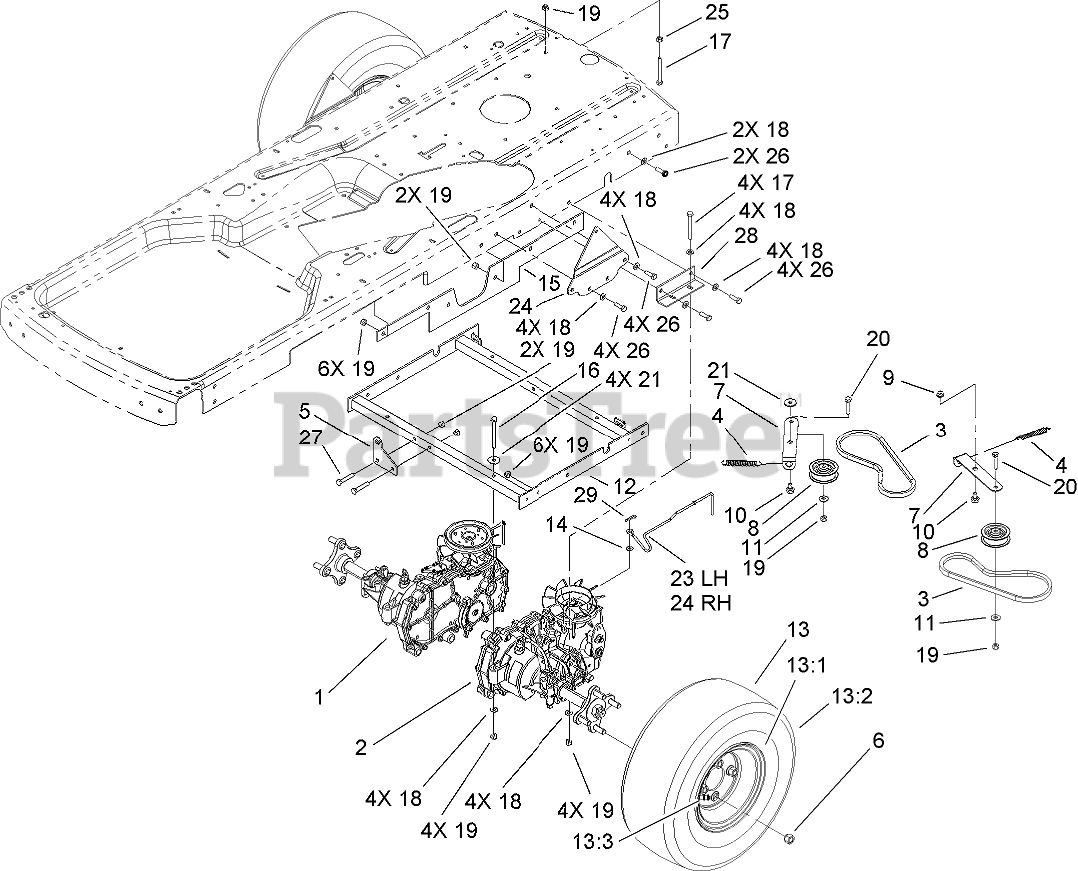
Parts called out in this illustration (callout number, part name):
1	TRANSAXLE-HYDRO, RH
2	TRANSAXLE-HYDRO, LH
3	V-BELT
4	SPRING
5	BRACKET-SPRING
6	NUT-LUG
7	ARM-IDLER
8	PULLEY-IDLER
9	NUT-HF
10	BOLT-SHOULDER
11	WASHER-FLAT
12	HYDRO FRAME ASM
13	REAR WHEEL ASM
13:3	STEM-VALVE
14	WASHER-FLAT
15	BRACE-FRAME, LEFT SIDE
16	SCREW-HH
17	SCREW-HH
18	WASHER-PLAIN
19	NUT-LOCK, NI
20	SCREW-HH
21	WASHER-PIVOT
23	ARM-BYPASS, LH
24	ANCHOR-DAMPER
25	NUT-HEX
26	SCREW-HH
27	SCREW-HH
28	SUPPORT-HYDRO
29	PIN-COTTER
